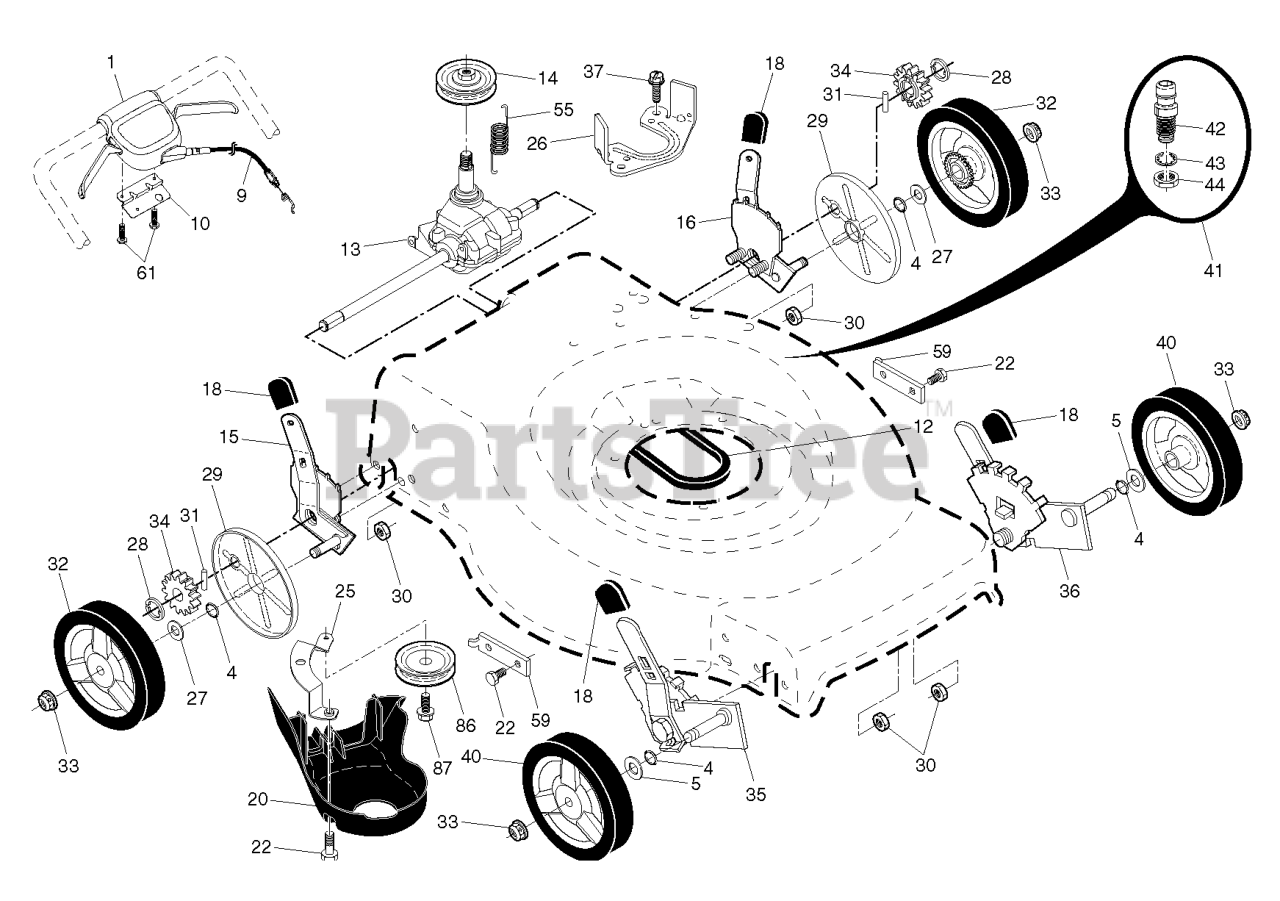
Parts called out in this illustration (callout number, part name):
1	CONTROL.AW2.22+RG.BS.GEN.BK/BK
4	O-RING..070X.487.NEOPRENE
5	WASHER.FLAT.1/2
9	CABLE.DRIVE.RWD.WALK.
10	BRACKET.DRIVE.CONTR.GEN2.BLACK
12	BELT.DRIVE.RWD+.SS.ZINC DUST
13	TRANSMISSION.22+AWD.WALK.MOWER
14	PULLEY.DRIVE.SM.AWD/RWD
15	HEIGHT ADJUSTER 9 POS QUICK
16	HEIGHT ADJUSTER 9 POS QUICK
18	SELECTOR KNOB
20	COVER.REAR.DRIVE.22+2013
22	BOLT.5/16HEX.WHS.HD
25	BRACKET.DRIVE.COVER.RGD.
26	BRACKET.TRANS.BELT.KEEPER.BZP
27	WASHER FLUT
28	E-RING 7/16 RE
29	COVER.DUST.WHEEL.INNER.WALK
30	NUT.HEX.FLANGE.1/4
31	PAWL, DRIVE
32	WHEEL.8X1.75.3SPK.RAD3.GREY
33	NUT.HEX.FLANGE.3/8-16.LO(3 2)
34	PINIION.14.TOOTH.RGD
35	ADJUSTER.ASM.9POS.LW.RGD.FR
36	ADJUSTER.ASM.LH FRONT/RH REAR
40	WHEEL & TIRES ASSY, FRONT
41	KIT.WASH-OUT.PORT.ZINC.WALK
42	WASHOUT.PORT.ZINC.RGD.22+
43	WASHER.LOCK.INTERNAL.TOOTH
44	LOCKNUT.HEX.WITH.O-RING
55	SPRING.RETURN.AUTO.
59	BRACKET.SUPPORT.22+RWGD.BZP
61	SCREW, PHILLIPS HEAD 10 X 5/8
86	PULLEY.RWD.IDLER.DBL SEAL
